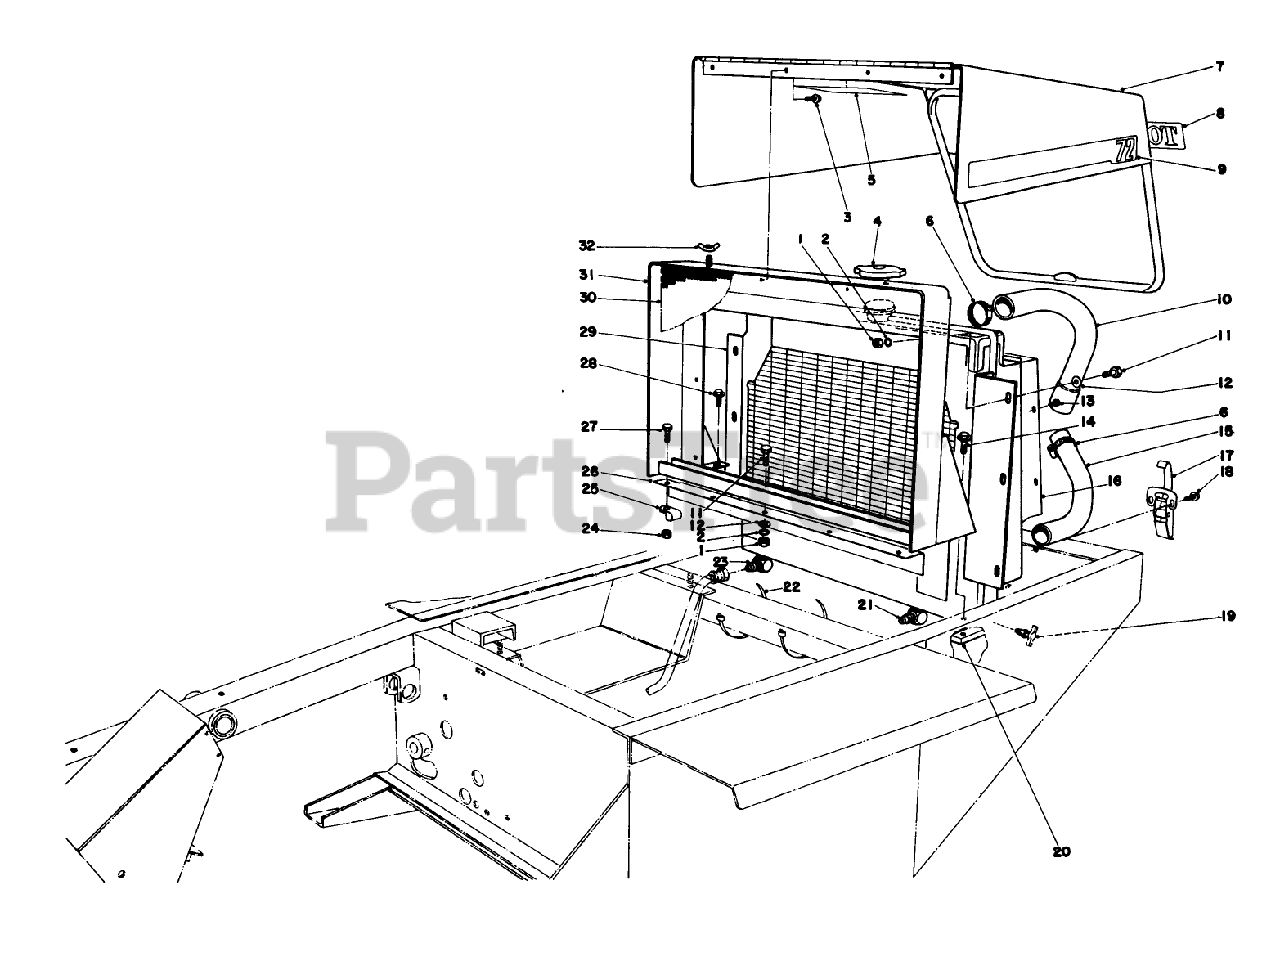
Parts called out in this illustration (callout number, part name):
1	NUT-HEX
2	WASHER-LOCK
3	SCREW-HWH
4	RAD PRESS CAP ASM
5	Decal
6	CLAMP-HOSE
7	Hood
8	Decal
9	DECAL
10	UPPER HOSE
11	SCREW-HH
12	WASHER-PLAIN
13	SCREW-THD FRM,HWH
14	SCREW-HHF
15	LOWER HOSE
16	Radiator Shroud
17	CLAMP-SLOTTED
18	10-24 X 1/2 SEMS SCR
19	DRAINCOCK
20	LH FRAME BAR
21	ELBOW
22	TIE-CABLE
23	ELBOW
24	NUT-HF
25	CLAMP-R
26	Sealing Plate Grill
27	SCREW-HH
28	SCREW-HWHTF
29	RADIATOR ASM
30	GRILLE WA R
31	Radiator Support
32	NUT-WING
